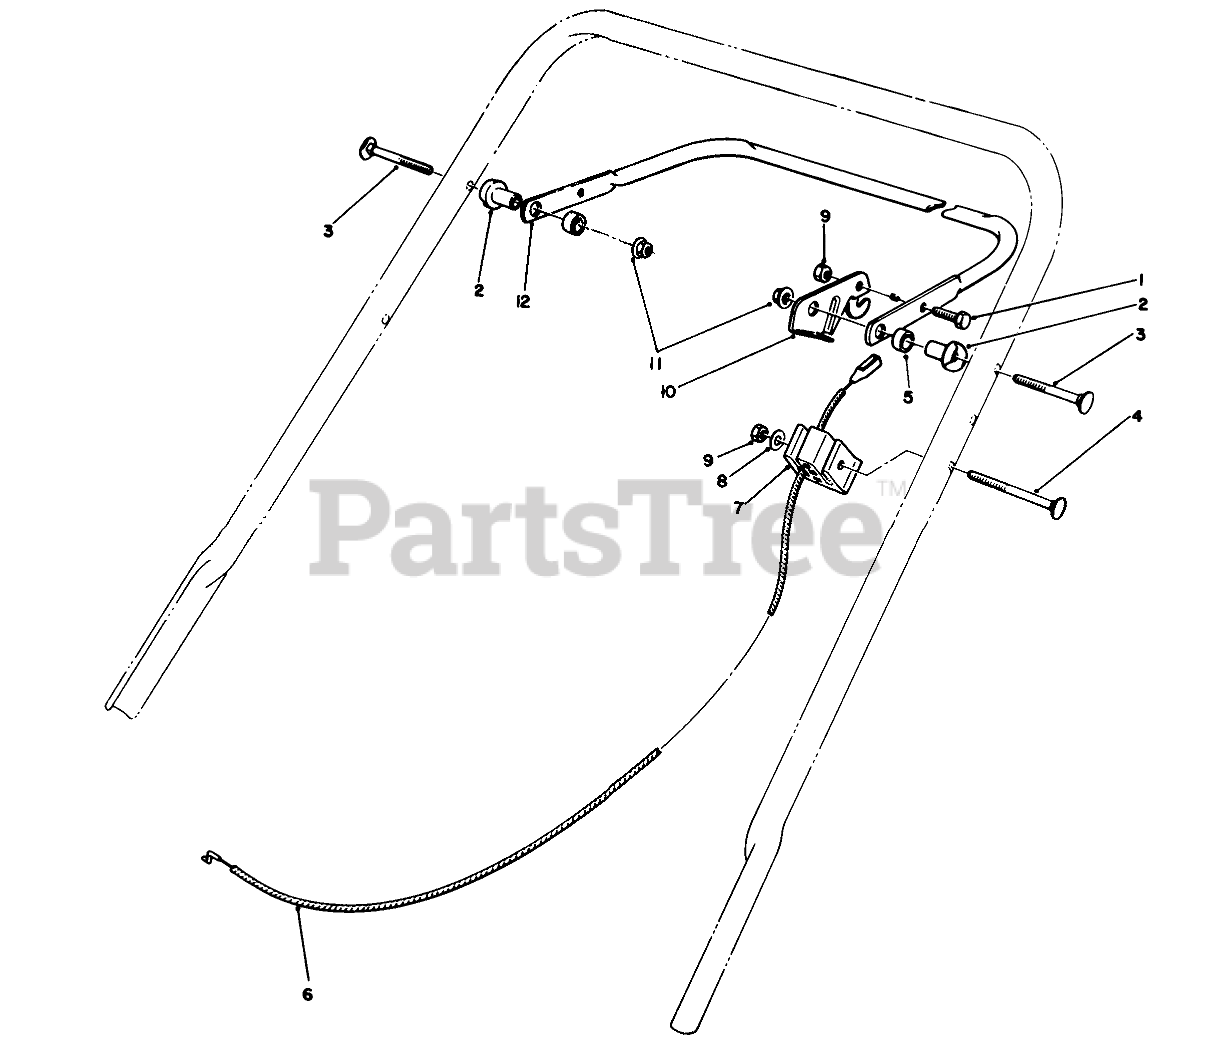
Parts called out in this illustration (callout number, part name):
1	SCREW-HH
2	SPACER-SUPPORT
3	5/16-18 X 2 HNDLE SCREW
4	HANDLE SCREW
5	SPACER-NYLON
6	BRAKE CONTROL
7	SUPPORT-CABLE
8	WASHER-FLAT
9	NUT-LOCK, NI
10	LEVER-CONTROL
11	NUT-LOCK, NI
12	Bar-Control
